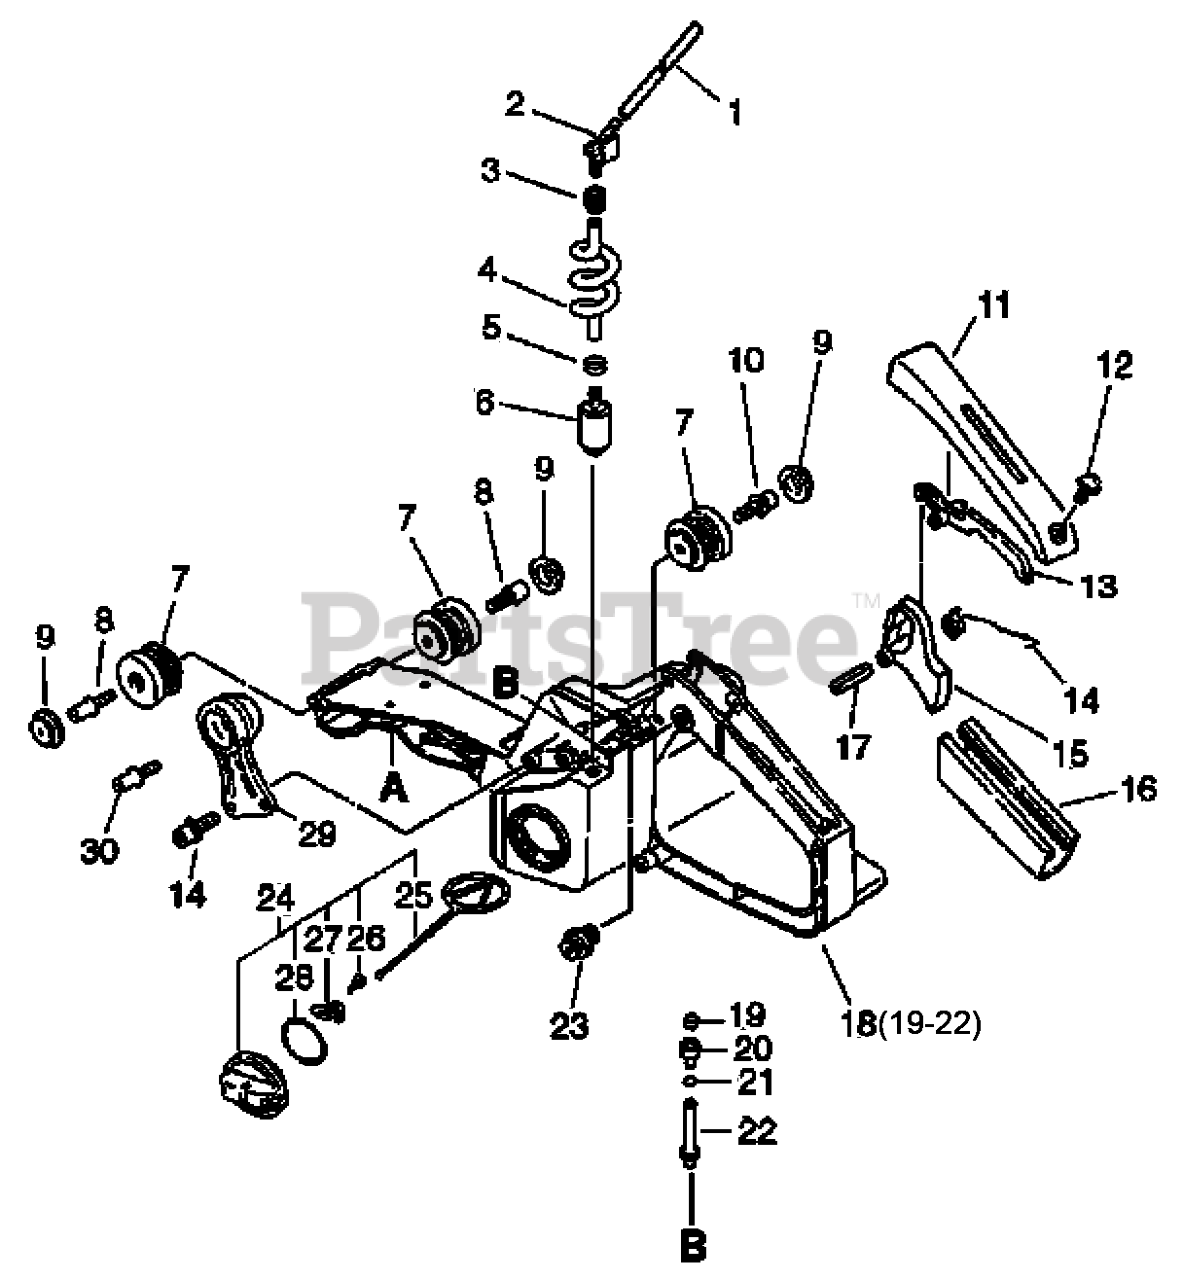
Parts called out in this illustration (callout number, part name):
1	PIPE, FUEL 3x6x100
2	CONNECTOR, PIPE
3	GROMMET
4	PIPE, FUEL
5	CLIP 6.5 MM
6	FILTER, FUEL
9	CAP, CUSHION
10	BOLT 5x14
11	COVER, HANDLE
12	SCREW 4x14
13	LEVER, THROTTLE LOCKOUT
14	SPRING, THROTTLE RETURN
15	TRIGGER, THROTTLE
16	GRIP, HANDLE
17	PIN, SPRING ?5x25 MM
18	HANDLE, REAR
19	VENT ASSY
20	HOLDER, VENT
21	CLIP 6.5 MM
22	PIPE, VENT
23	LATCH, THROTTLE
24	CAP ASSY, FUEL
25	CONNECTOR, CAP L= 60 MM
26	SCREW, TAPPING 3x8
27	RETAINER, CONNECTOR
28	O-RING 29
